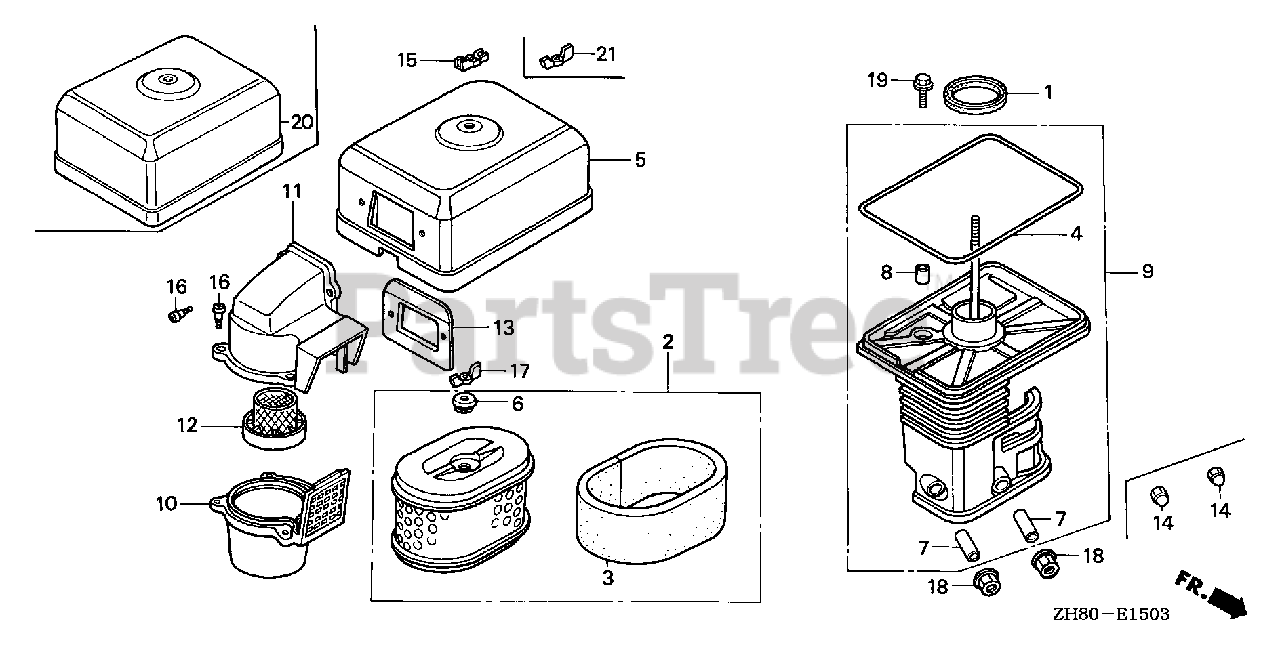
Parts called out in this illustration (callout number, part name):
1	GASKET, ELBOW
2	ELEMENT, AIR CLEANER (DUAL)
3	FILTER (OUTER)
4	GASKET, AIR CLEANER COVER
5	COVER, AIR CLEANER (DUAL)
6	GROMMET, AIR CLEANER
7	COLLAR, AIR CLEANER
8	COLLAR B, AIR CLEANER
9	ELBOW, AIR CLEANER
10	CASE, PRE AIR CLEANER
11	CAP, PRE AIR CLEANER
12	GUIDE, PRE AIR CLEANER
13	PLATE, PRE AIR CLEANER
16	BOLT, SPLASH GUARD
17	NUT, TOOL BOX SETTING
18	NUT, FLANGE (6MM)
19	BOLT, FLANGE (6X20)
21	NUT, TOOL BOX SETTING
